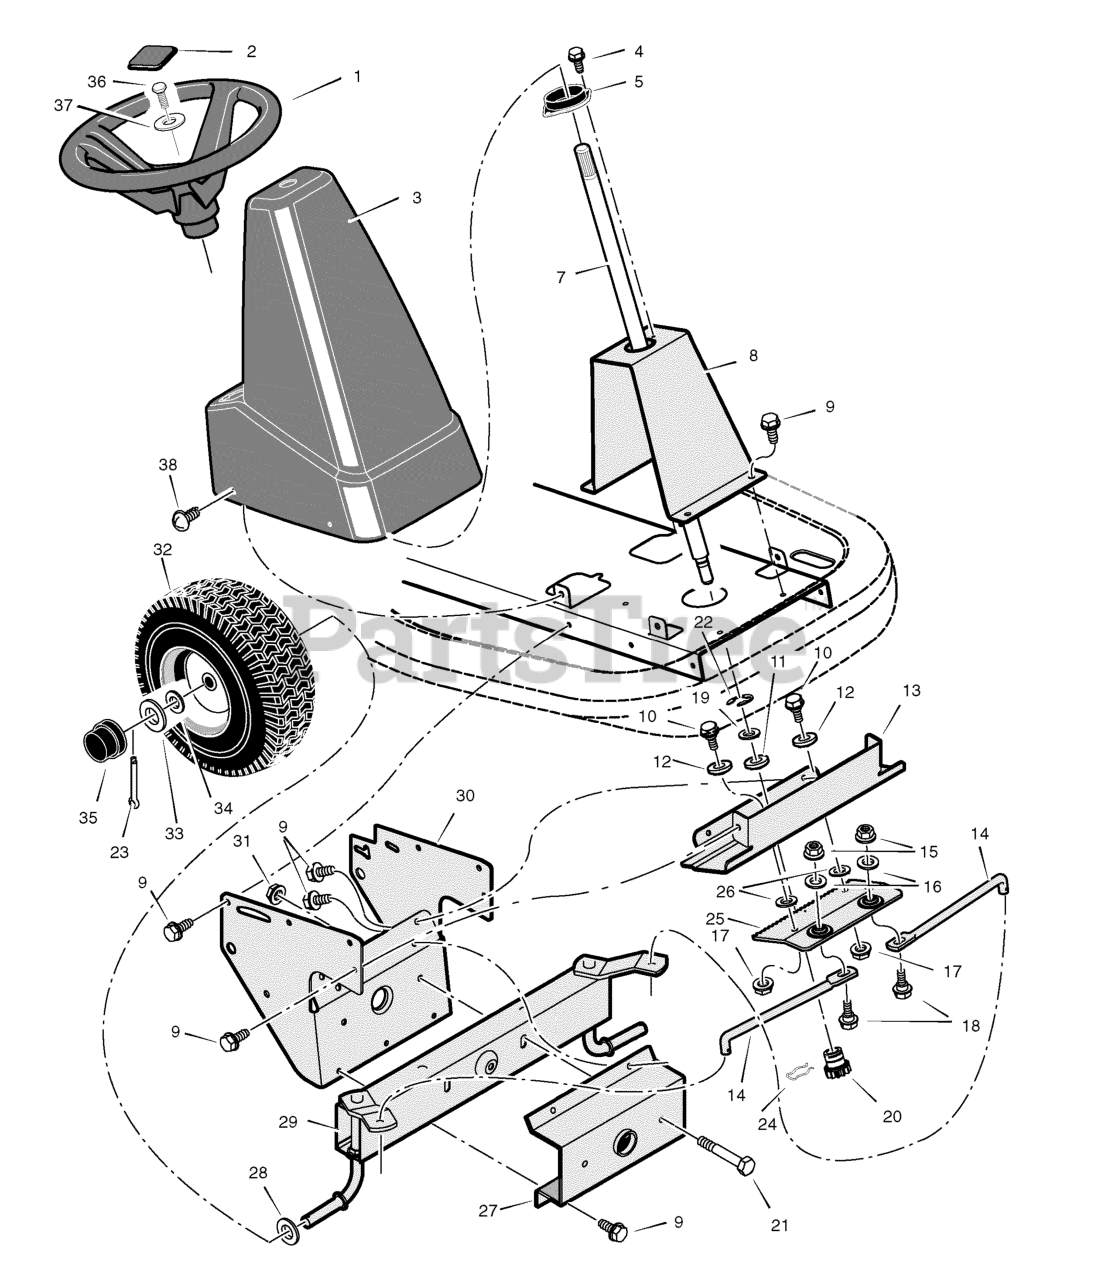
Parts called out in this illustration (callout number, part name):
1	Wheel, Steering
2	Cap, Steering (Black)
3	Console, High (Black)
5	Bearing, Upper Steering
7	Shaft, Steering
8	Support, Steering
9	Screw
10	Bolt, Shoulder
11	Bearing, Lower Steering
12	Roller
13	Plate, Gear Mounting
14	Link, Drag
15	Nut, Flange
16	Washer
17	Nut, Flange
18	Bolt, Hex
19	WASHER, 1-1.3 16G FLT
20	Gear, Pinion
21	Bolt, Hex
22	E-Ring, Retainer
23	Pin, Cotter
24	Retainer, Spring
25	Rack, Steering
26	Washer
27	Bracket, Axle Front
28	Washer
29	Axle & Spindle Assembly
30	Bracket, Support
31	Nut, Flange
32	Wheel, Front *
33	Washer
34	Washer
35	Cap, Hub
36	Screw, Hex
37	Washer
38	Screw
